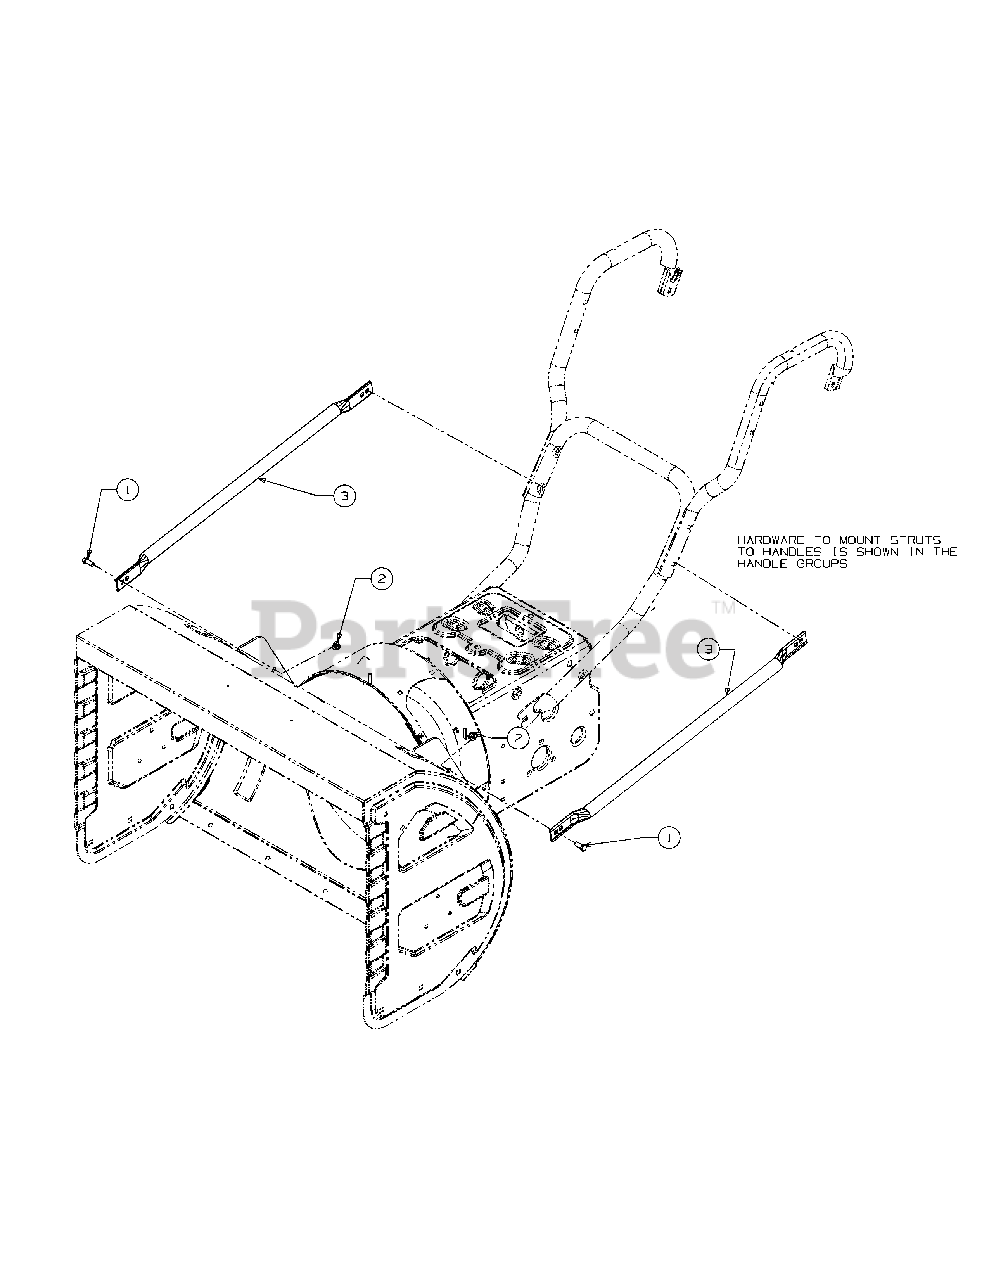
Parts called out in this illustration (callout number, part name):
1	Screw-Hex 5/16 X 3
2	Nut-Flglk 5/16-18
3	Tube-Suppo
